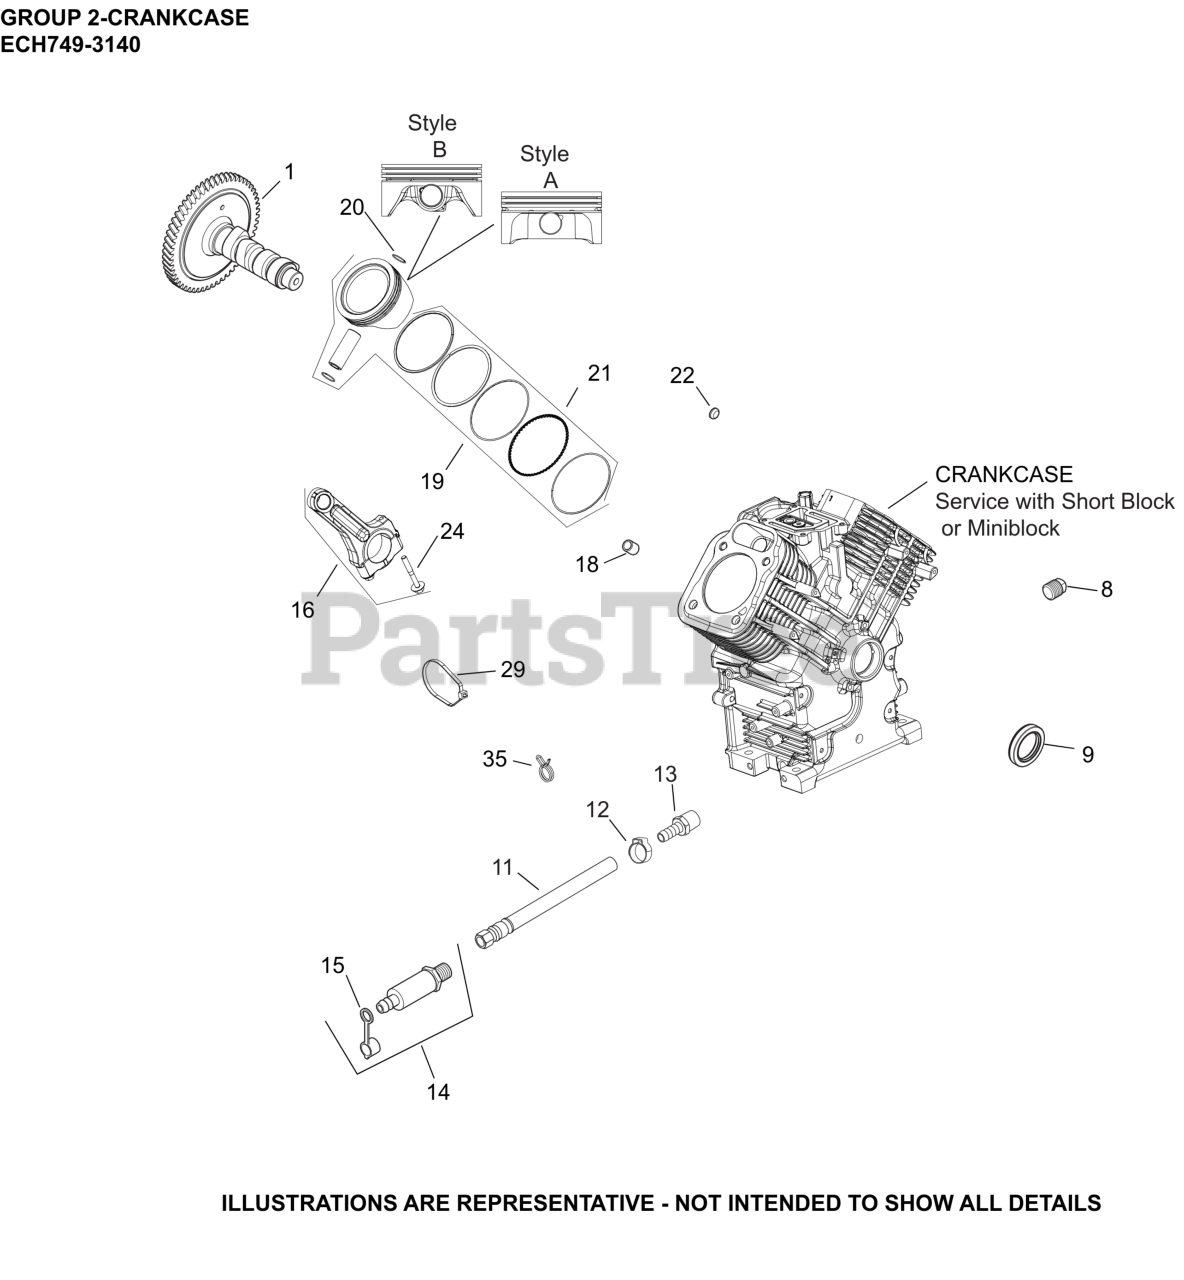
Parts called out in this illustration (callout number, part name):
1	KIT, CAMSHAFT
8	PLUG, SQ HD PIPE 3/8"
9	SEAL, OIL (HELIX LIP)
11	HOSE, OIL
13	FITTING, BARBED
14	KIT, OIL DRAIN VALVE
15	CAP, OIL DRAIN VALVE
16	ROD, ASSEMBLY CONNECTING
18	PIN, LOCATING
19	KIT,PSTN/RNG STYLE B(STD)
19	KIT,PSTN/RNG STYLE B(.08)
19	KIT,PSTN/RNG STYLE B(.25)
19	KIT,PSTN/RNG STYLE B(.50)
20	RETAINER, PISTON PIN
21	RING SET(STD)STYLE B-1.2mm Tp RING THICK
21	RING SET(.08)STYLE B-1.2mm RING THICK
21	RING SET(.25)STYLE B-1.2mm Tp RING THICK
21	RING SET(.50)STYLE B-1.2mm Tp RING THICK
22	PLUG, CUP
24	KIT, ROD BOLTS-(#25086677S)
35	CLAMP, HOSE
